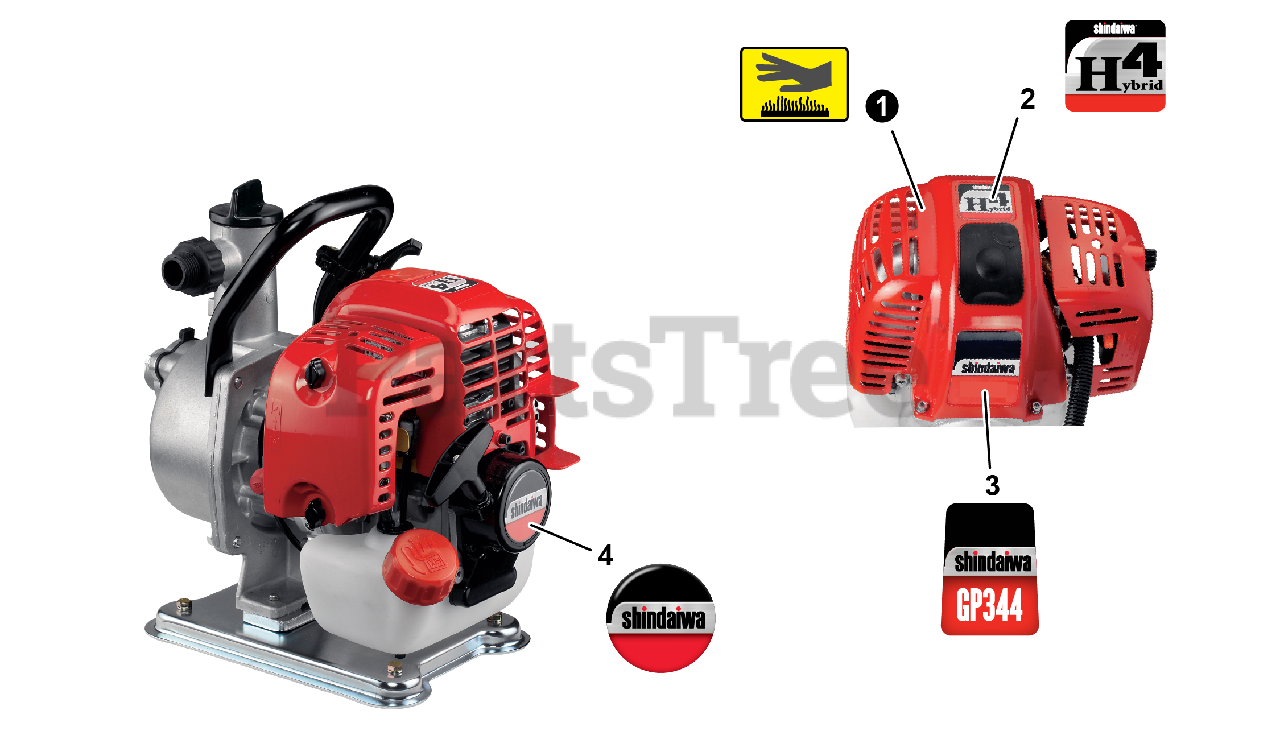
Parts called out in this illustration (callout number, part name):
1	LABEL, CAUTION - HOT
2	LABEL, shindaiwa H4
3	LABEL, GP344
4	LABEL, RECOIL STARTER
